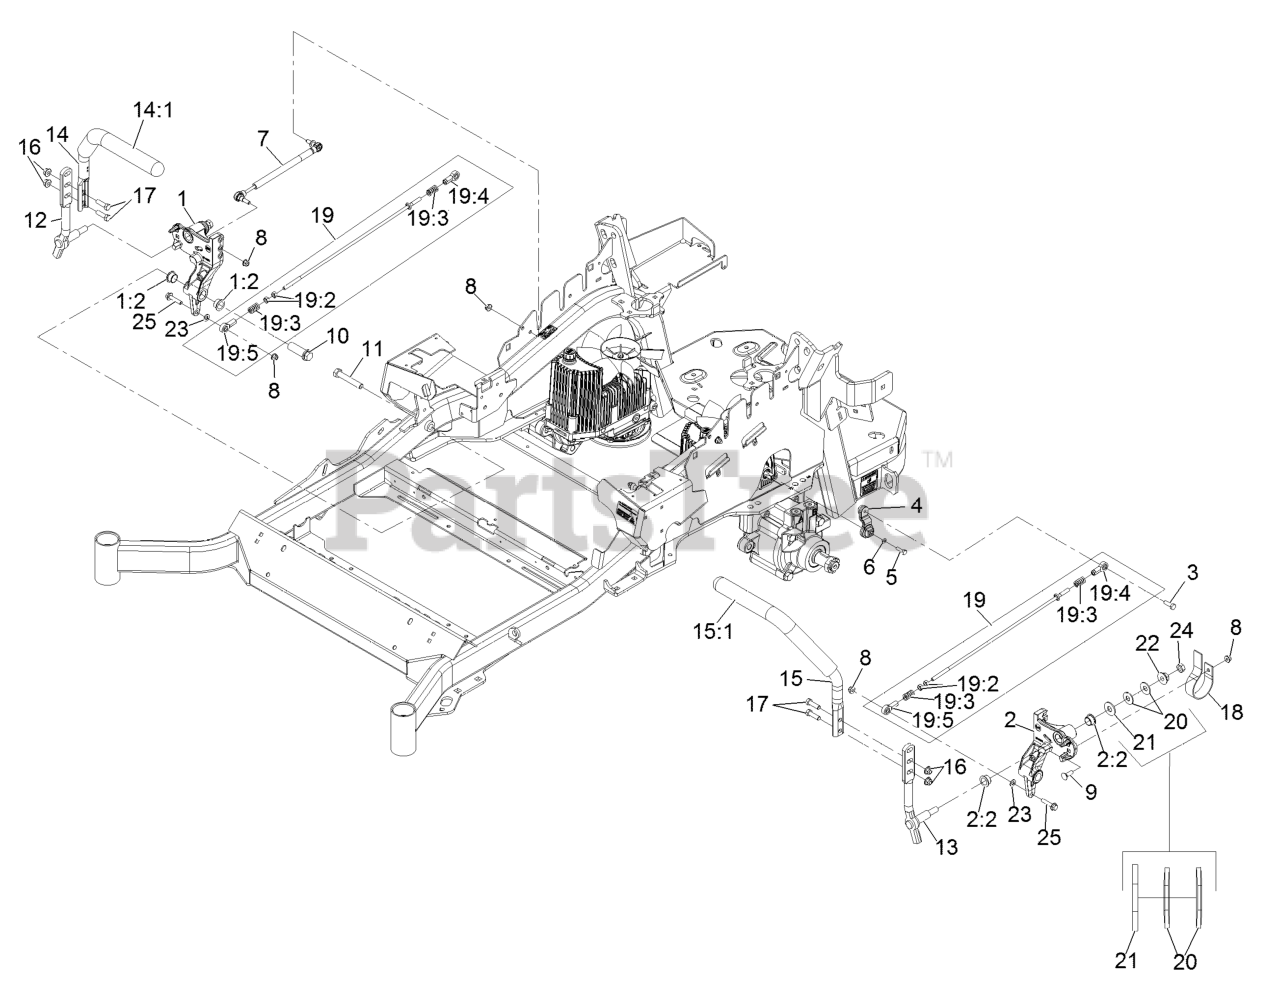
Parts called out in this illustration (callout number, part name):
1	RH MOTION CONTROL AND BUSHING ASM
1:2	BUSHING-FLANGE
2	LH MOTION CONTROL AND BUSHING ASM
2:2	BUSHING-FLANGE
3	SCREW-HH, THREAD LOCKING
4	ARM-CONTROL, PUMP
5	SCREW-HH
6	WASHER-SPRING
7	DAMPER-CONTROL, MOTION
8	NUT-HF, NI
9	BOLT-CARR
10	HUB-THREADED
11	SCREW-HH
12	LEVER-CONTROL MOTION, RH
13	LEVER-CONTROL MOTION, LH
14	RH STEERING HANDLE ASM
14:1	GRIP-LEVER, CONTROL
15	LH STEERING HANDLE ASM
15:1	GRIP-LEVER, CONTROL
16	NUT-HF, NI
17	SCREW-HH
18	SPRING-LEAF
19	PUMP LINKAGE REAR ASM
19:2	NUT-HEX
19:3	SPRING-COMPRESSION
19:4	BALLJOINT-LH
19:5	BALLJOINT-RH
20	WASHER-SPRING
21	WASHER-FLAT
23	WASHER-PLAIN
24	NUT-JAM
25	SCREW-HHF
